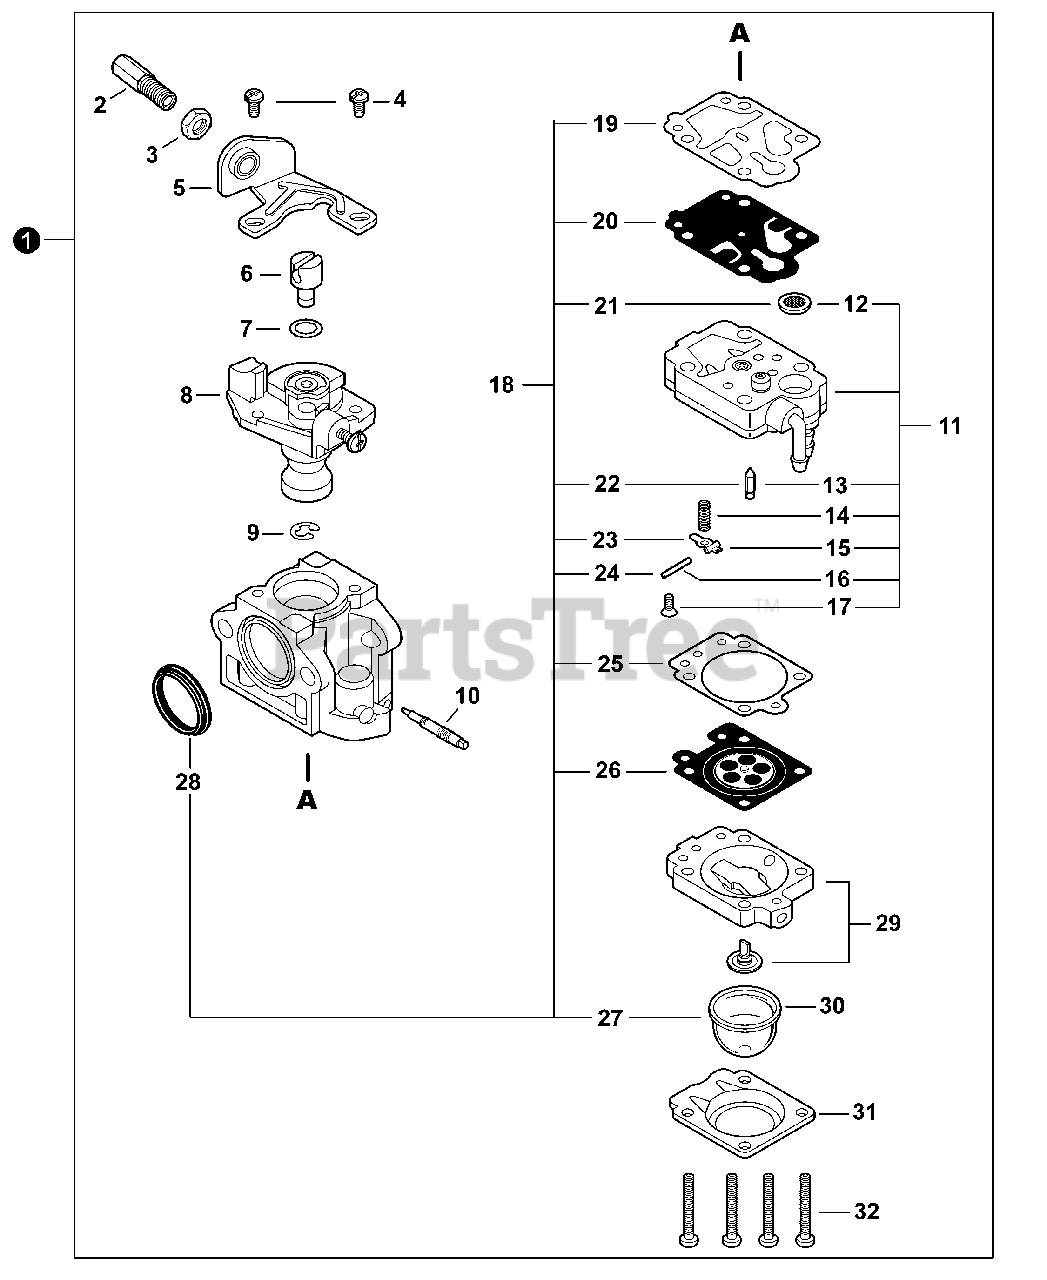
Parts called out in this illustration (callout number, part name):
1	CARBURETOR - WYK-366
2	ADJUSTER, THROTTLE CABLE
3	NUT, ADJUSTER LOCK M7
5	BRACKET, THROTTLE CABLE
8	VALVE ASSY, THROTTLE
10	NEEDLE, HIGH SPEED
11	BODY ASSY, PUMP
12	SCREEN, FUEL INLET
13	VALVE, INLET NEEDLE
14	SPRING, METERING LEVER
15	LEVER, METERING
16	PIN, METERING LEVER
17	SCREW
18	REPAIR KIT, CARBURETOR
19	GASKET, PUMP
20	DIAPHRAGM, PUMP
21	SCREEN, FUEL INLET
22	VALVE, INLET NEEDLE
23	LEVER, METERING
24	PIN, METERING LEVER
25	GASKET, METERING DIAPHRAGM
26	DIAPHRAGM, METERING
27	BULB, PURGE
28	RING, PACKING
29	BODY ASSY, PURGE
30	BULB, PURGE
31	RETAINER, PURGE BULB
